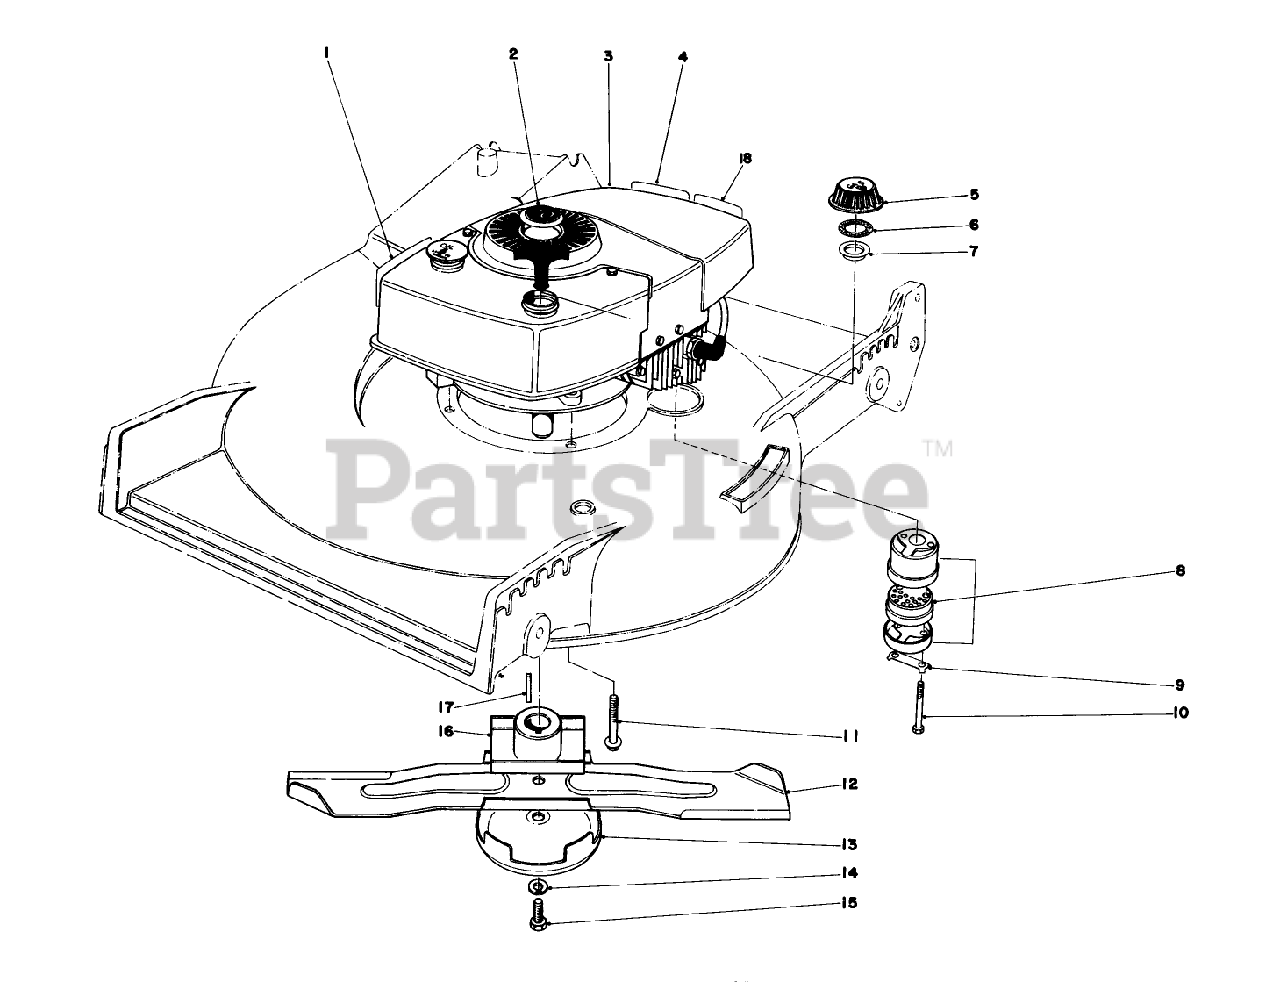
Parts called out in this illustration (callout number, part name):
3	Engine
6	GASKET
8	MUFFLER ASM
9	CLIP - LOCKING
10	SCREW-HH
14	WASHER-LOCK
15	BLADE SCREW
17	KEY-SQUARE
